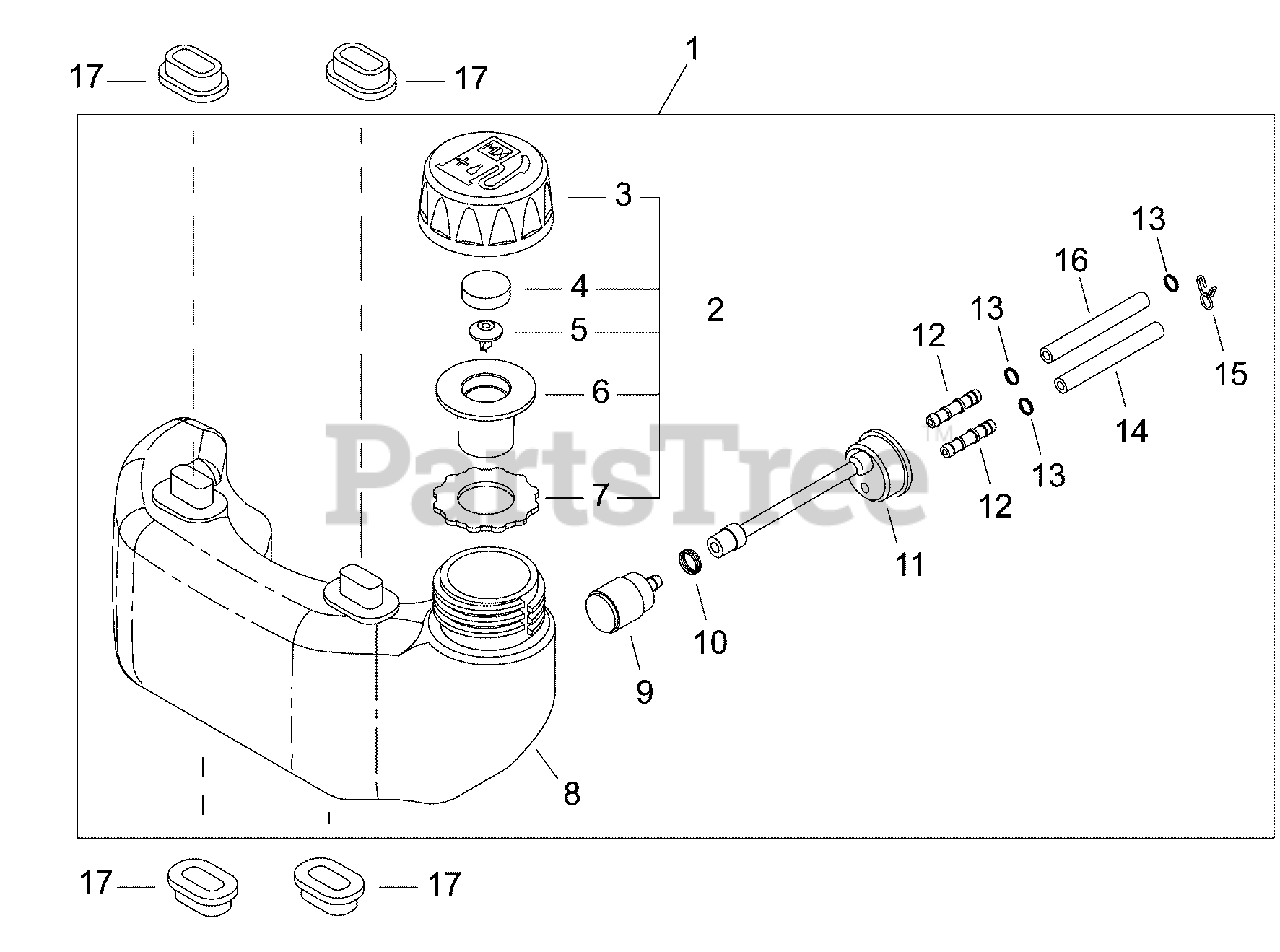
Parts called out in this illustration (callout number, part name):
1	TANK ASSY, FUEL
2	CAP ASSY, FUEL
3	CAP, FUEL
4	PACKING, VENT
5	VENT ASSY
6	HOLDER, VENT
7	GASKET, FUEL CAP
8	TANK, FUEL
9	FILTER, FUEL 125-528
10	CLIP
11	GROMMET, FUEL WITH PIPE
12	CONNECTOR, PIPE
13	CLIP Ø6
14	PIPE, FUEL RETURN
15	CLIP, SPRING Ø5.2
16	PIPE, FUEL
17	CUSHION, FUEL TANK
